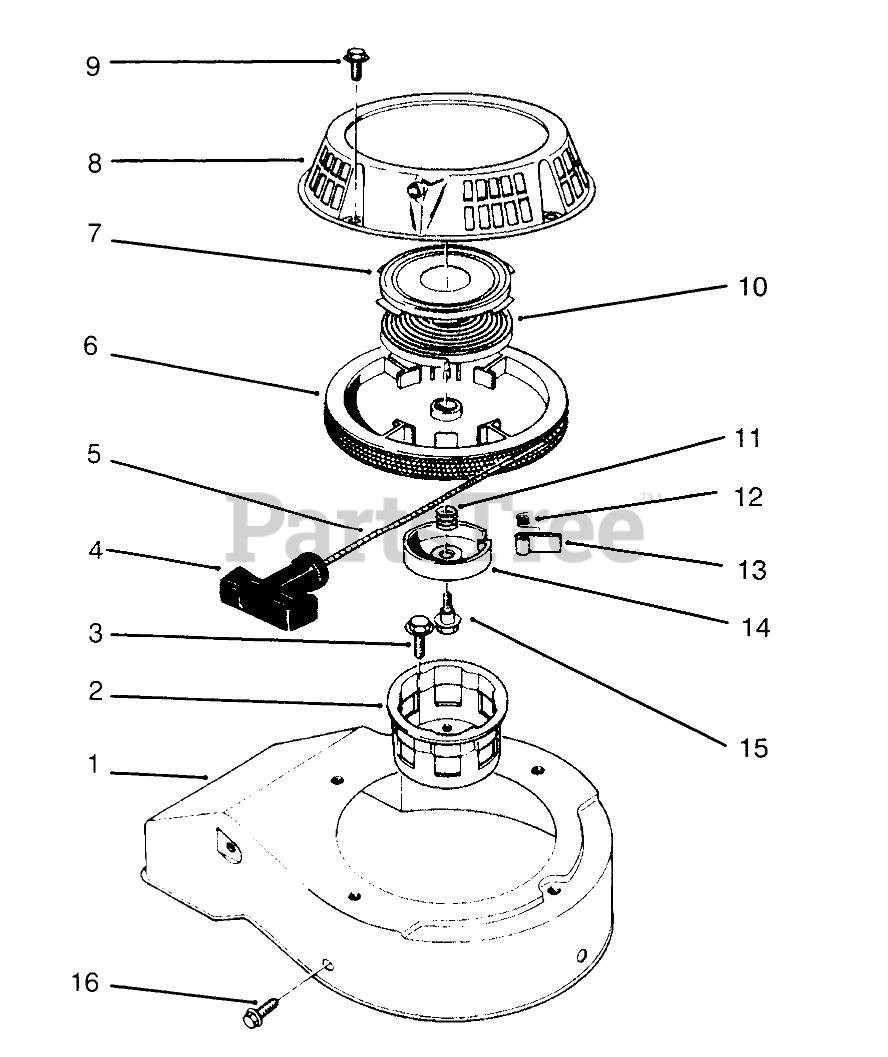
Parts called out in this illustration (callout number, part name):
1	Cover-Cooling Fan
2	PULLEY-CUP, STARTER
4	HANDLE-RECOIL
5	ROPE-STARTER
7	Retainer-Spring, Recoil
8	CASE-STARTER
9	SCREW-HHF
10	Spring-Recoil
11	SPRING
12	SPRING
14	RETAINER
